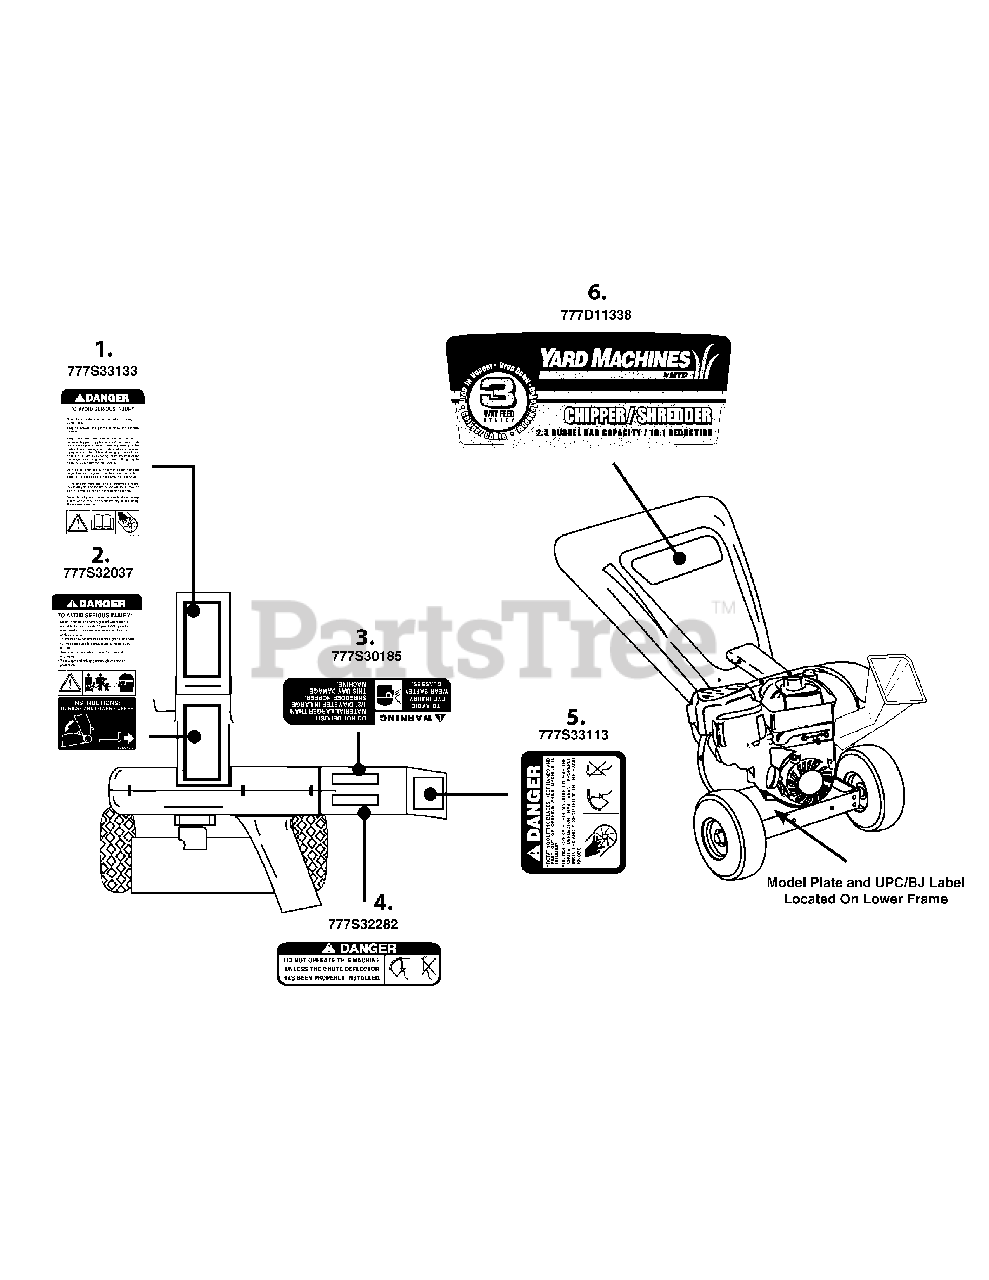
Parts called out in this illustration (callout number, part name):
1	LABEL:CS:400:LGCHUTE:DANGER
2	LABEL-DANGER CHIPP
3	LABEL CHP/SHRD
4	LABEL-CHUTE
5	LABEL-CHIPPER SHREDDER CHUTE
6	LABEL:CS:HOPR:YMRED:452DEPOT
